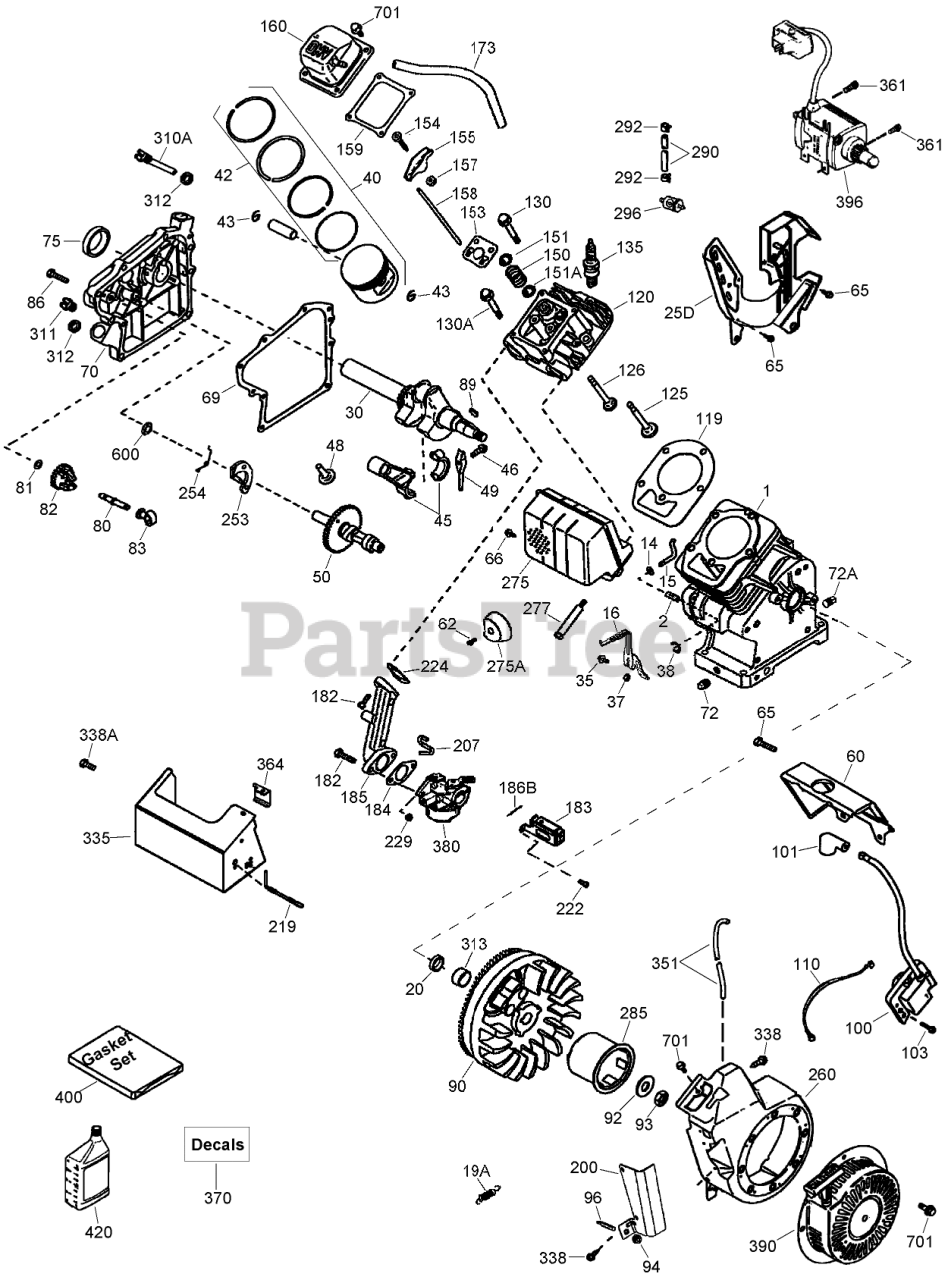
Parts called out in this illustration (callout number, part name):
1	Cylinder ASM (Includes 2, 20, 72, 72A)
2	Pin-Dowel
14	Washer
15	Rod-Governor (Includes 38)
16	Lever-Governor
19A	Spring-Governor
20	Seal-Oil
25D	Baffle-Air
30	Crankshaft
35	Screw (T-25, 10-32 X 63/64)
37	Nut-Square
38	Ring-Retaining
40	Piston, Pin and Ring Set (Std) (Includes 41, 42, 43)
40	Piston, Pin and Ring Set (.010 O S) (Includes 41, 42, 43)
42	Ring Set (STD)
42	Ring Set (.010 O S)
43	Ring-Retaining, Piston Pin
45	Connecting Rod Asm (Includes 46, 49)
46	Bolt-Rod, Connecting
48	Lifter-Valve
49	Dipper-Oil
50	Camshaft
60	Extension-Housing, Blower
62	Screw (8-32 x 3/8)
65	Screw (10-24 x 9/16)
66	Screw (1/4-20 x 27/32)
69	Gasket-Cover, Cylinder
70	Cover-Cylinder (Includes 75 -83, 311)
72	Plug-Drain, Oil (SQH 1/4-18)
72A	Plug-Pipe (Internal Hex, 1/4-18)
75	Seal-Oil
80	Shaft-Governor
81	Washer-Flat
82	Governor Gear ASM (Includes 81)
83	Spool-Governor
86	Screw (1/4-20 x 1-1/4)
89	Key-Flywheel (also available in Packaged Part 740007B)
90	Flywheel (18 Watt, Ring Gear)
92	Washer-Belleville
93	Nut-Flywheel
94	Nut (10-32)
96	Bolt-Adjusting, R.P.M.
100	Ignition-State, Solid
101	Cover-Spark Plug
103	Screw (T-15, 10-24 x 15/16)
110	Wire-Ground
119	Gasket-Head, Cylinder
120	Head-Cylinder (Includes 151A)
125	Valve-Exhaust (STD) (Includes 151)
125	Valve-Exhaust (1/32 O S) (Includes 151)
126	Valve-Intake (STD) (Includes 151, 151A)
130	Screw (5/16-18 x 1-1/2)
130A	Screw (5/16-18 x 2-41/64)
